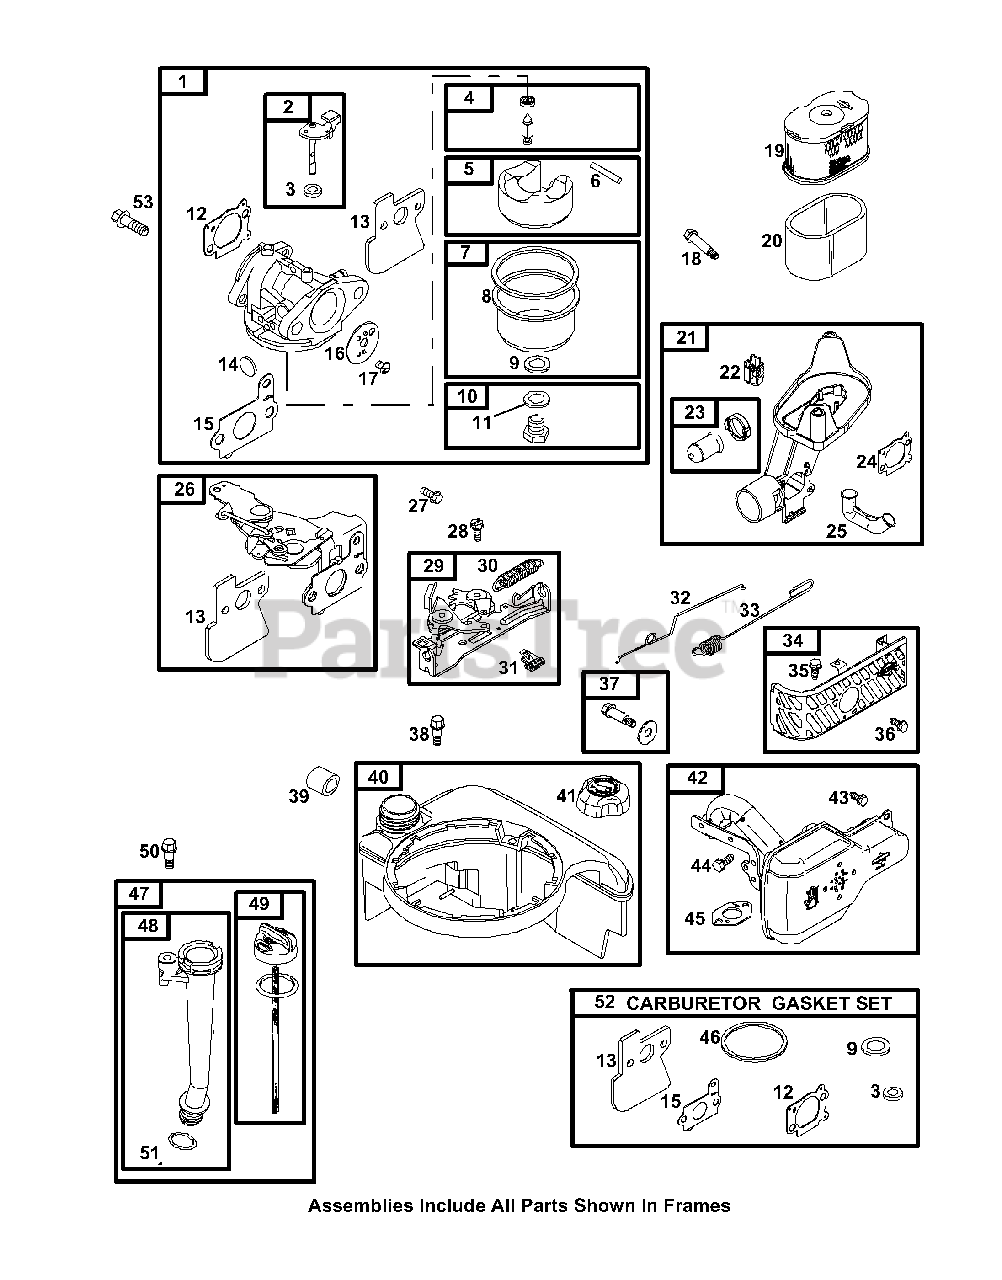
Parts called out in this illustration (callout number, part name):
1	Carburetor
2	Shaft-Throttle
3	Seal-Throttle Shaft
4	Kit-Needle/Seat
5	Float-Carburetor
6	Pin-Float Hinge
7	Bowl-Float
8	Gasket-Float Bowl
9	Washer-Sealing
11	Washer-Sealing
12	Gasket-Air Cleaner
13	Spacer-Carburetor
14	Plug-Welch
15	Gasket-Intake
16	Valve-Throttle
17	Screw (Throttle Valve)
18	Screw (A/C Primer Base)
19	Filter-A/C Cartridge
20	Filter-Pre-Cleaner
21	Base-A/C Primer
22	Bracket-Casing Clamp
23	Primer-Carburetor
24	Gasket-Air Cleaner
26	Bracket-Control
27	Screw (Control Bracket)
28	Screw (Brake)
29	Brake
30	Spring-Brake
31	Switch-Stop
32	Link-Mechanical Governor
33	Spring-Governor
34	Guard-Muffler
35	Screw (Muffler Guard)
36	Screw (Muffler Guard)
37	Screw/Washer Kit
38	Screw (Fuel Tank)
39	Spacer-Fuel Tank
40	Tank-Fuel
41	Cap-Fuel Tank
43	Screw (Exhaust Muffler)
44	Screw (Exhaust Muffler)
45	Gasket-Exhaust
46	Gasket-Float Bowl
47	Assembly-Dipstick/Tube
48	Tube-Dipstick
50	Screw (Oil Fill Tube)
51	Seal-O Ring (Dipstick Tube)
52	Gasket Set-Carburetor
53	Screw (Carburetor)
